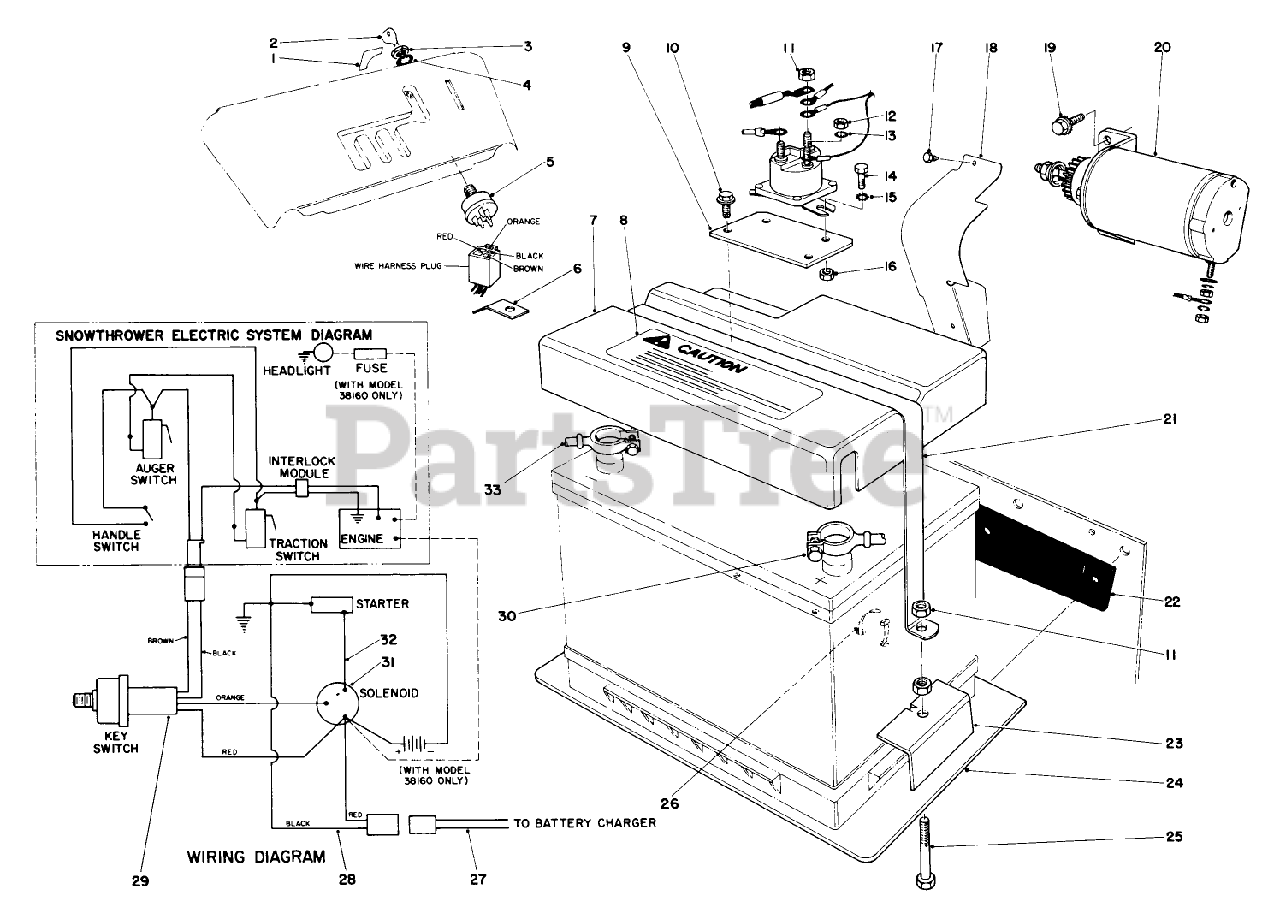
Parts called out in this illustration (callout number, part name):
4	WASHER-LOCK
10	SCREW-HWH
11	NUT-HEX
12	NUT-HEX
13	WASHER-LOCK, INT
14	SCREW-HH
15	WASHER-LOCK/EXT
16	NUT-LOCK, NI
18	BRIGGS 280265
19	5/16-18X3/4 HX HD SEM
20	Starter Motor Pinion Assy.
25	SCREW-HH
26	TIE-CABLE
27	MALE WIRE ASM
30	BATT-SOLENOID CABLE
31	SOLENOID
